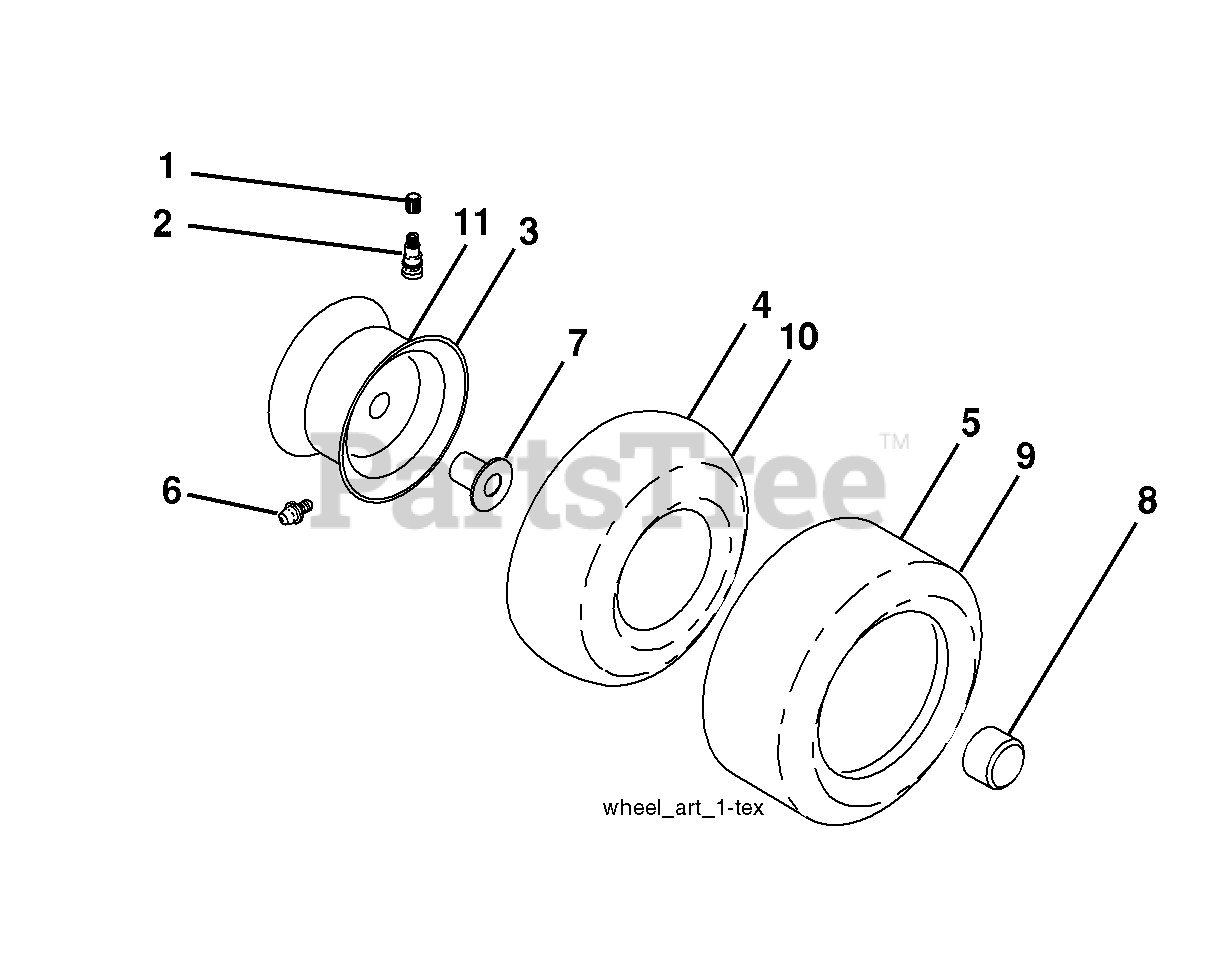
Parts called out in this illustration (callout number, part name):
1	Cap Valve Tire
2	Stem Valve
3	Rim Asm 6" Front
4	Tube Front
5	Tire Front 15 x 6.0-6 Service
6	Fitting Grease
7	Bearing Flange
8	Cap Axle Blk 1 50 x 1 00
9	Tire Rear 18 x 9.5-8 "Turf Saver"
9	Tire Rear 18 x 9.5-8 "Turf Saver LT"
10	Tube Rear
11	Rim Asm 8" Rear
11	Sealant, Tire
